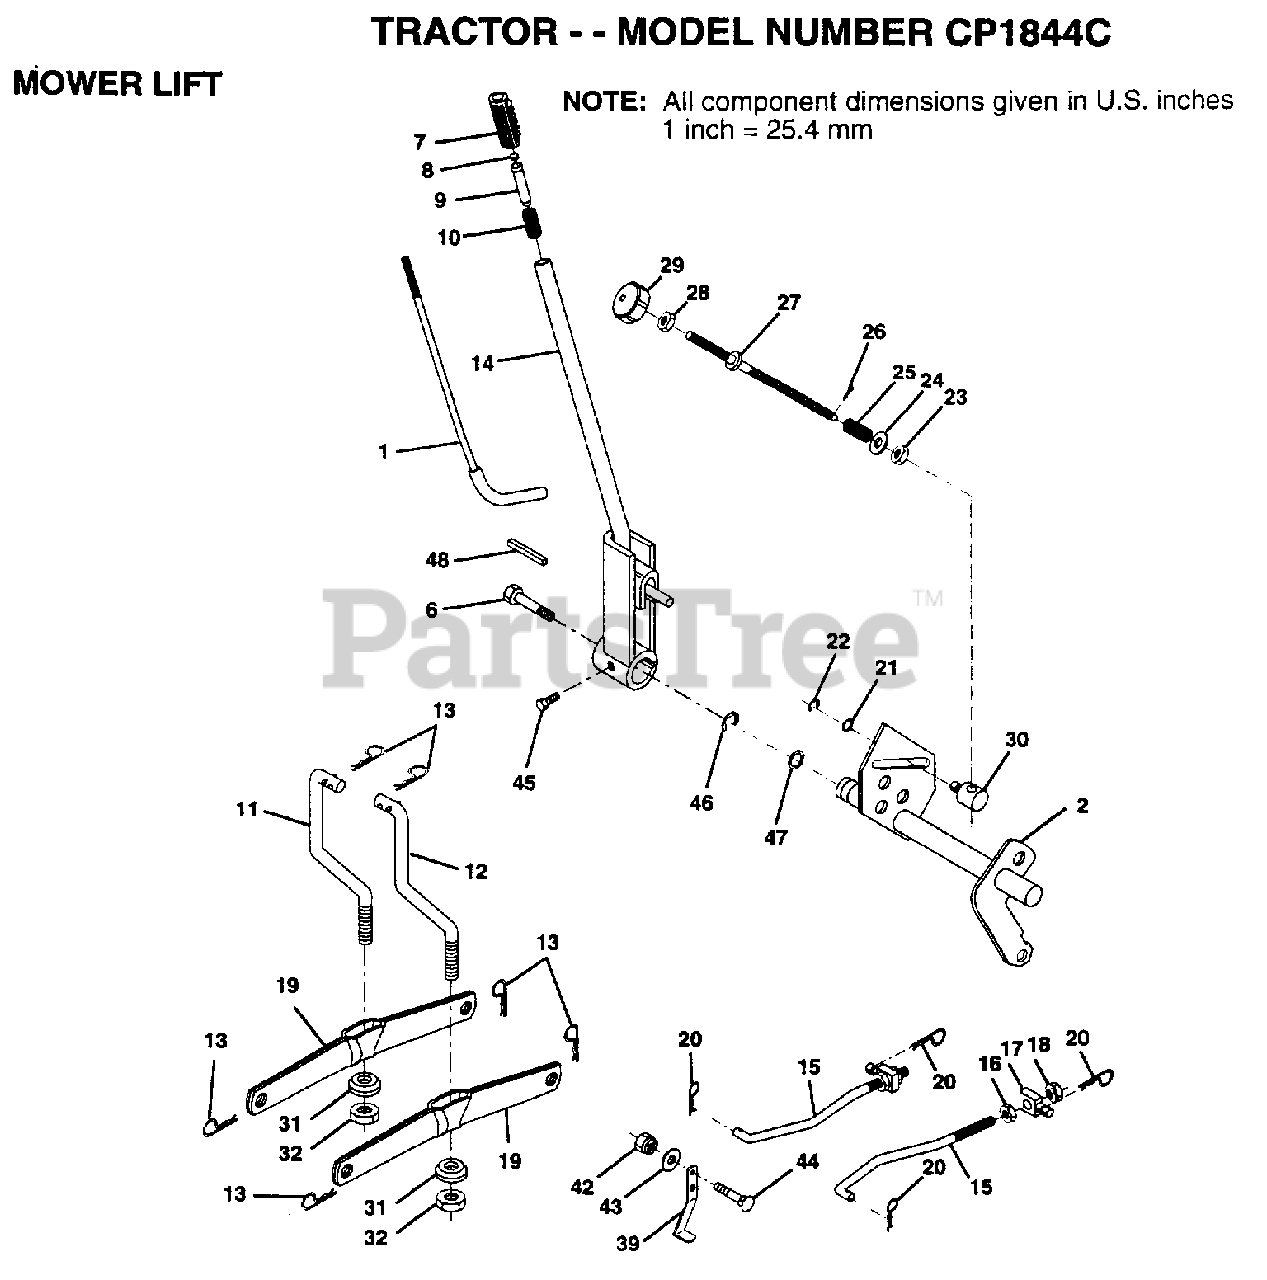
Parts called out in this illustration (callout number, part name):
1	ROD ASS'Y LEVER
6	"BOLT,HEX"
7	GRIP
10	SPRING T
11	LINK.LIFT.LH.GTV
12	LINK.LIFT.RH.GTV.
15	LINK.FRONT
16	NUT
17	TRUNION
18	NUT.LK.W/WSH.1/2.
19	ARM SUSP REAR
20	RETAINER.SPRING
21	WASHER
22	KLIP RING
23	NUT T
24	WASHER
25	SPRING.COMP.INF.H
27	ROD.ADJ.LIFT
28	NUT
29	KNOB INF 3/8-16
30	TRUNION LT
31	BEARING PVT LH
32	NUT.CROWNLOCK.3/8
39	STOP.OVER.CENTER
43	WASHER GT
44	BOLT
46	E-RING
47	WASHER
